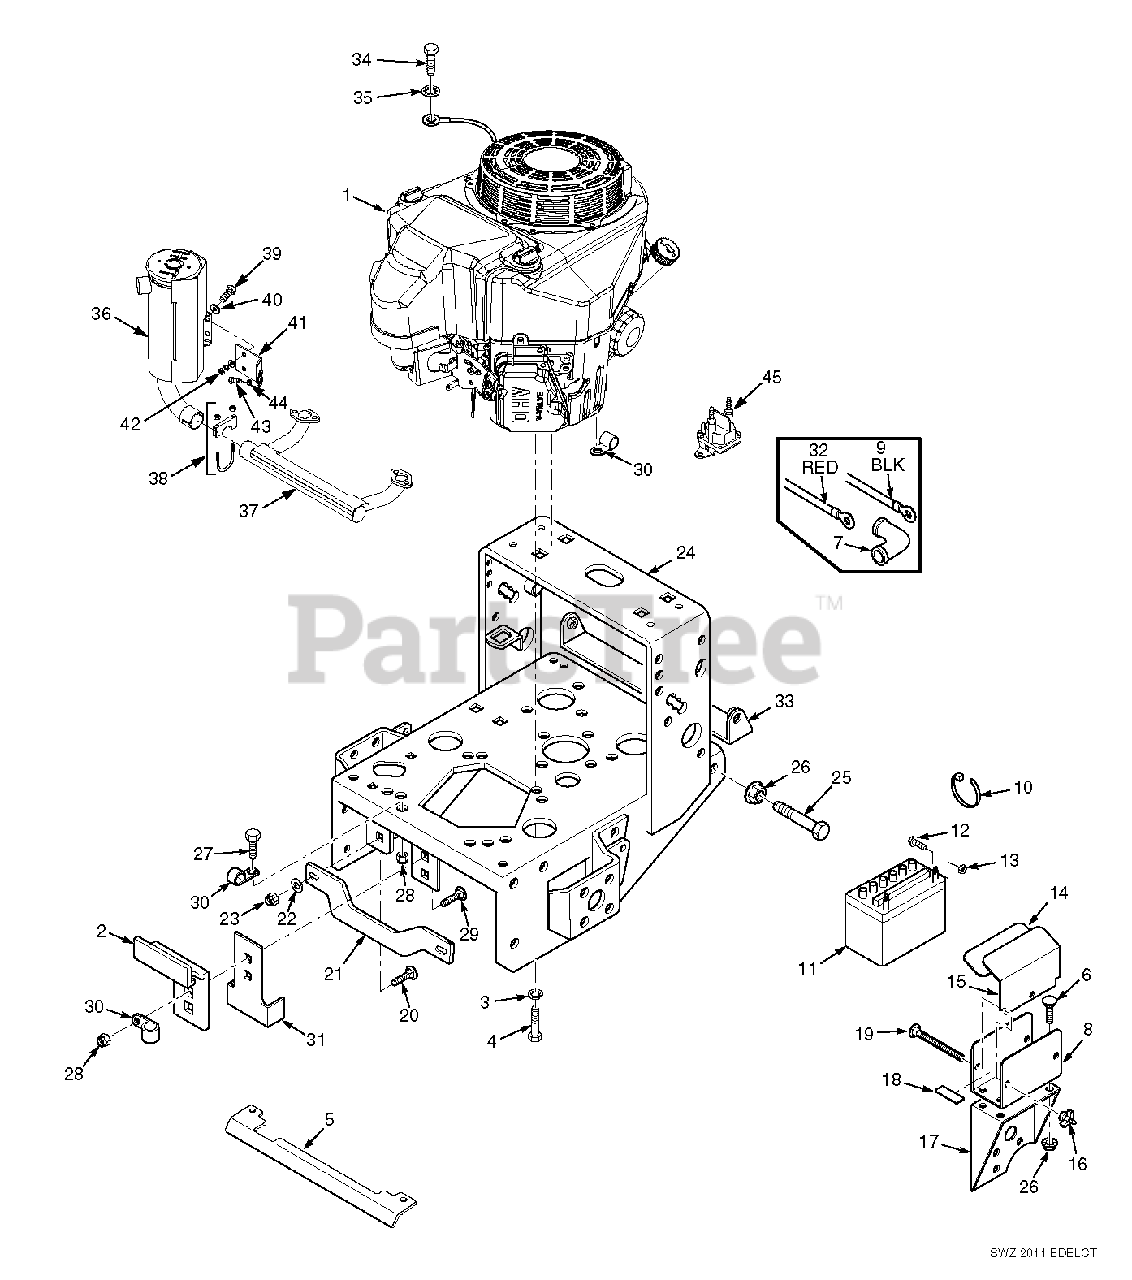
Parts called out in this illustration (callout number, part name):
1	Engine
2	Plate, Clutch Bracket
3	Lock Washer 3/8"
4	Bolt, Hex Head 3/8-16 x 1-1/4"
5	Heatshield, 20" Large Frame
6	Carriage Bolt, 5/16-18 x .75"
7	Rubber Boot
8	Battery Box
9	Battery Cable, 31.5" Black
10	Cable Tie
11	Battery
12	Bolt, 1/4-20 x 1/2"
13	Nut, 1/4-20
15	Battery Cover
16	Wing Nut, 1/4-20
17	Battery Support
18	Pad, Rubber
19	Bolt, 1/4-20 x 6" Carriage
20	Carriage Bolt, 3/8-16 X 1-1/4"
21	Brace, 20" Large Frame
22	Flat Washer .391 x .938 x .105
23	Nut, 3/8-16 Elastic Stop
24	Engine Deck, 20" Wide, w/decals
25	Bolt, 5/16-18 x 2" Hex Head
26	Nut, 5/16-18 Serr. Flange
27	Hex Head Bolt, 5/16-18 x .75"
28	Nut, 5/16-18 Elastic Stop
29	Carriage Bolt, 5/16-18 x 1"
31	Clutch Bracket
32	Battery Cable, 25" Red
33	Pulley Guard, 20" Frame
34	Bolt, Hex Head M8-1.25 x 16
35	Lockwasher, 5/16" Ext. Tooth
36	Muffler
37	Exhaust Manifold
38	Clamp, Muffler 1-1/2" Dia.
39	Bolt, Hex Head 5/16-18 x 1"
40	Flatwasher, 5/16-.344 x .688 x .065
41	Bracket, Muffler
42	Nut, 5/16-18
43	Bolt, Hex Head M8-1.25 x 16
44	Lockwasher, 5/16" Spring
45	Solenoid
